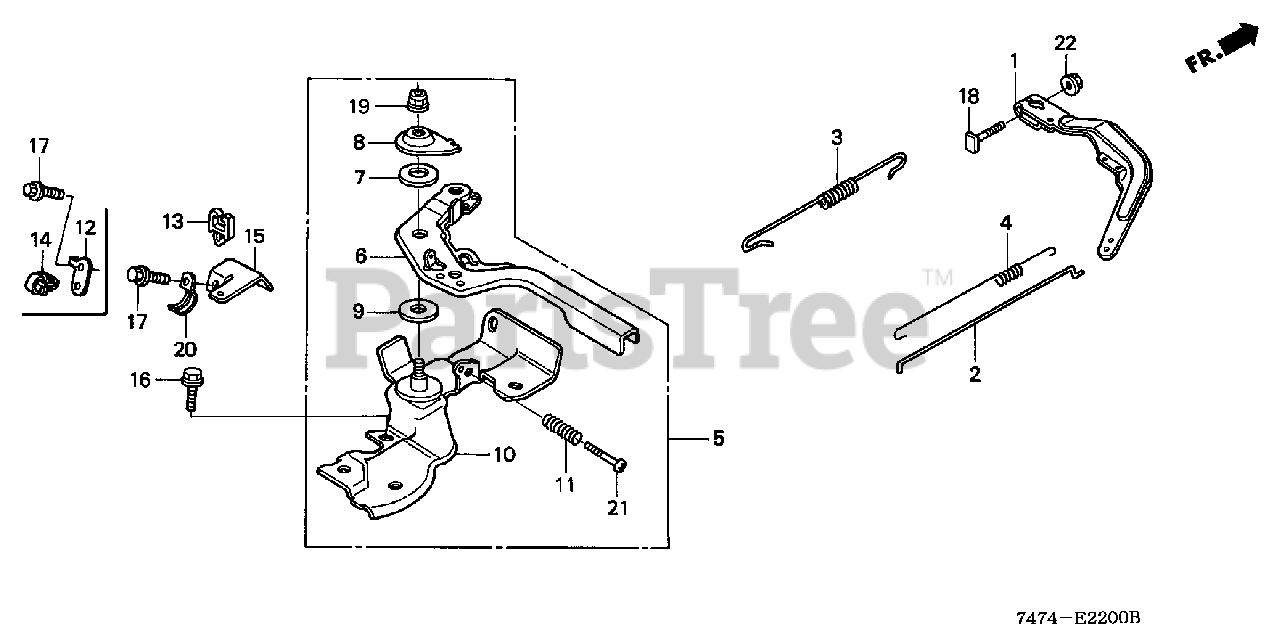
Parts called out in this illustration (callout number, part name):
1	ARM, GOVERNOR
2	ROD, GOVERNOR
3	SPRING, GOVERNOR
4	SPRING, THROTTLE RETURN
5	CONTROL ASSY.
6	LEVER, CONTROL
7	SPRING, LEVER
8	WASHER, CONTROL LEVER
9	SPACER, CONTROL LEVER
10	BASE, CONTROL
11	SPRING, CONTROL ADJUSTING
13	CLIP, TURN SIGNAL WIRE
15	BRACKET, GROUND WIRE
16	BOLT, FLANGE (6X12) (CT200)
17	BOLT, FLANGE (6X14)
18	BOLT, GOVERNOR ARM
19	NUT, SELF-LOCK (6MM)
21	SCREW, PAN (5X25)
22	NUT, FLANGE (6MM)
